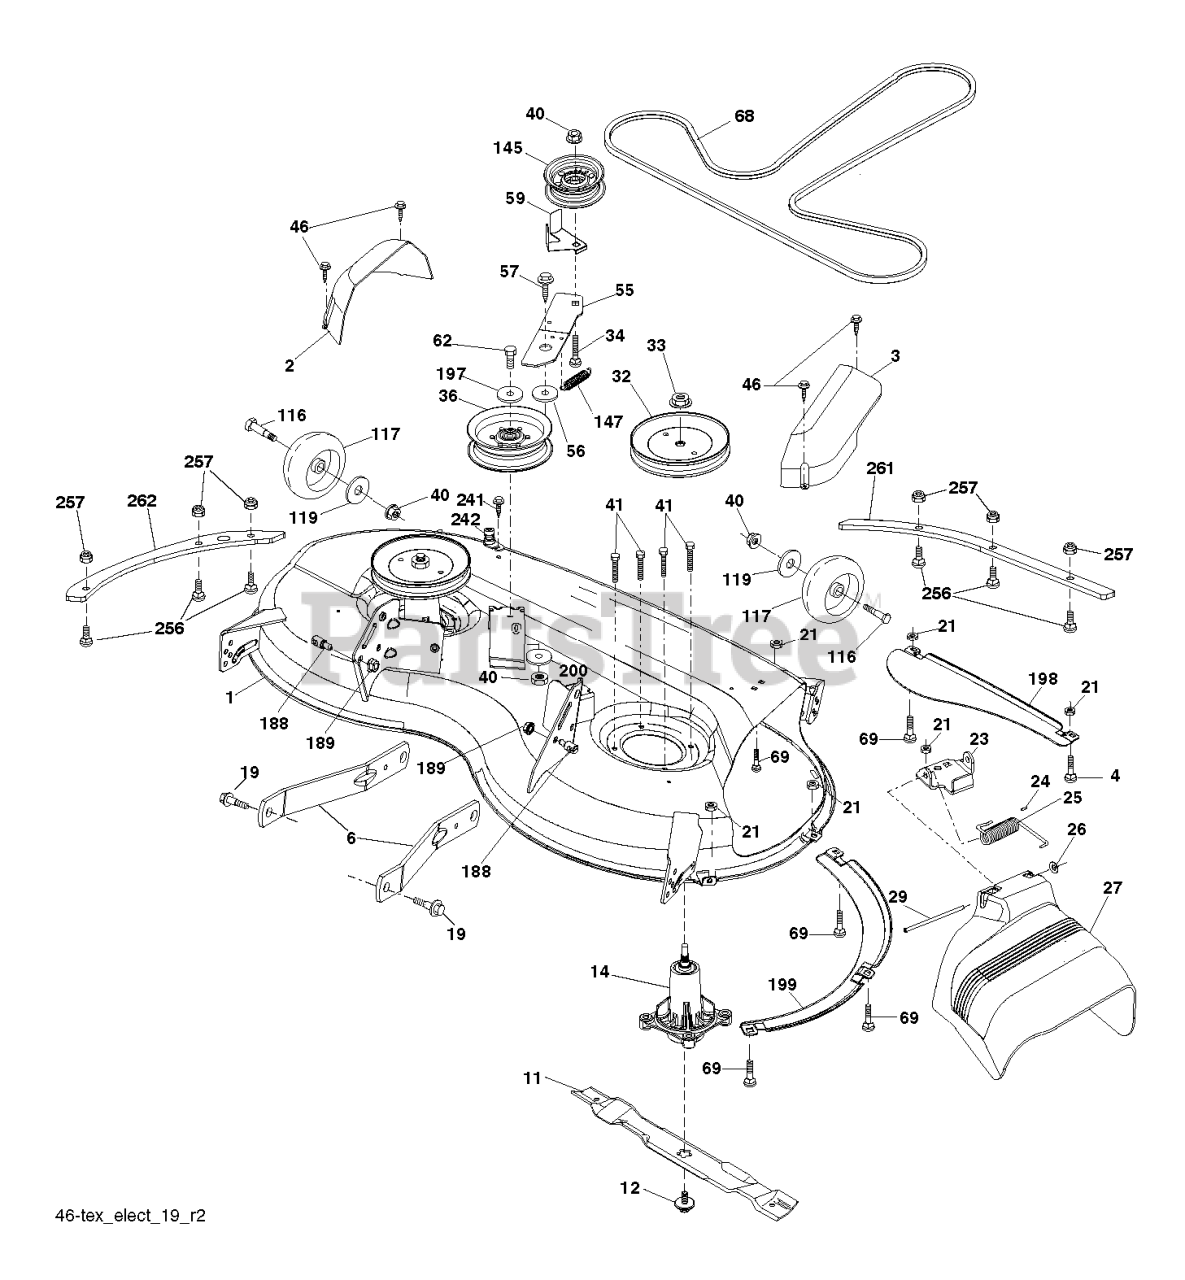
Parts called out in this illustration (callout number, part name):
1	KIT.SVC.WELDMNT.46"405050X498
2	COVER.MANDREL.LH.46"
3	COVER.MANDREL.RH.46"
4	SCREW HEXAGON HEAD SCREW 5/16-
6	ARM.SUSPENSION.MOWER.R
11	BLADE.MOWER.46".HI.LIFT
12	SCREW.SEMS.7/16-20X1.HEX.HEAD
14	KIT.MANDREL.NONGREASE.TALL
19	BOLT.SHOULDER
23	BRKT.DEFLECTOR.38"2005+
24	CAP-SLEEVE LT
25	SPRING.TORSION.DEFLECT
26	NUT PUSH M
27	SHIELD.DEFLECTOR.MOWER.46"BLAC
32	PULLEY.MANDREL.5.438.PD
34	GSPW Bolts
36	PULLEY.IDLER.2006
40	NUT LOCK FLG 3/8-16 UNC
41	BOLT.HEX.WASHR.HED.313-18X1.19
46	SCREW.1/4-20X5/8
56	SPACER.RETAINER
57	SCREW 3/8-16X1
59	GUARD, BELT
62	BOLT-HEX EAK
68	V-BELT
117	WHEEL.GAUGE.RALLY.NARROW
145	PULLEY.IDLER.48"PRIMARY
147	SPRING.MOWER.DRIVE.ELECTRIC
188	STUD.FASTNER.W/ANTI-ROTATE
198	BAFFLE CENTER FRONT
199	BAFFLE FRONT RH
200	WASHER.13/32 X 1 X 1/2.11GUARD
241	SCREW.TT.#10-32X.5.3/8.FLANGE
242	PORT.WASHOUT
256	BOLT CUP HEAD SQUARE NECK BOLT
257	NUT T
261	PLATE.REINF.DECK.46".FRONT.BLK
262	PLATE.REINF.DECK.46".SIDE.BLK
